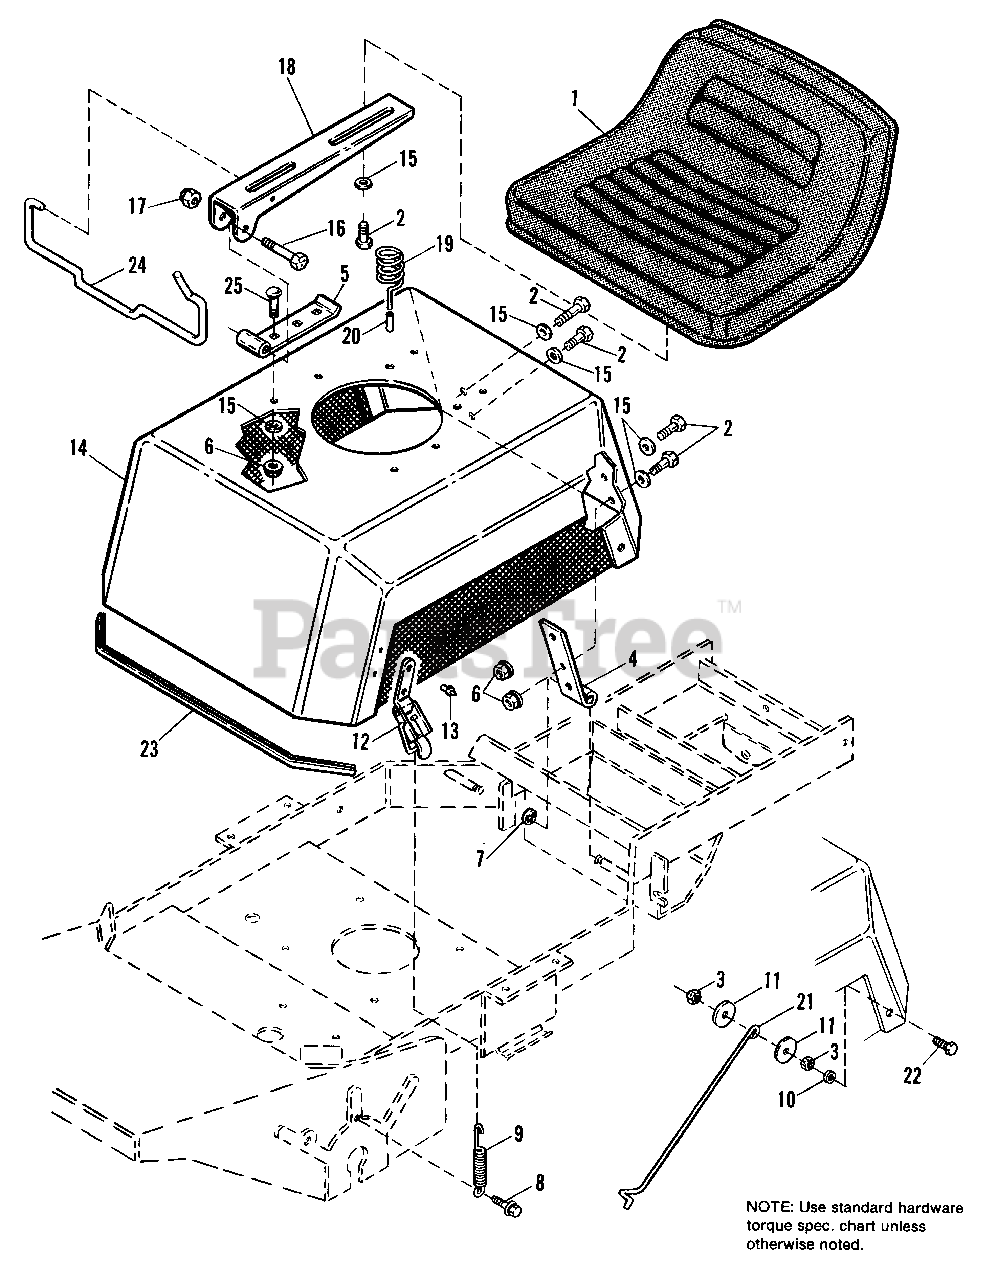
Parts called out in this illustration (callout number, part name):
2	CAPSCREW, Hex Hd., 5/16-18
3	NUT, Hex Centerlock, 1/4-20
4	HINGE, Seat Deck
5	HINGE, Lower Seat
6	NUT, Hex, Whizlock, 5/16-18
7	RING, Retaining
8	SCREW, Taptite, 5/16-18
9	SPRING, Latch
10	WASHER, 1/4
11	WASHER, 1/4 x 1-1/4
12	LATCH, Seat, Pull Tight
13	RIVET, Seat Latch
14	DECK, Seat (1691654)
14	DECK, Seat (1691658)
15	WASHER, Flat, 5/16
16	CAPSCREW, 3/8-16 x 2
17	NUT, Hex Esna Lock, 3/8-16
18	HINGE, Upper, Seat
19	SPRING, Seat
20	COVER, Spring
21	ROD, Seat Deck
22	CAPSCREW, 1/4-20 x 1-1/4
23	MOLDING, Deck
24	LATCH, Seat
25	CARRIAGE BOLT, 5/16-18 x 3/4
